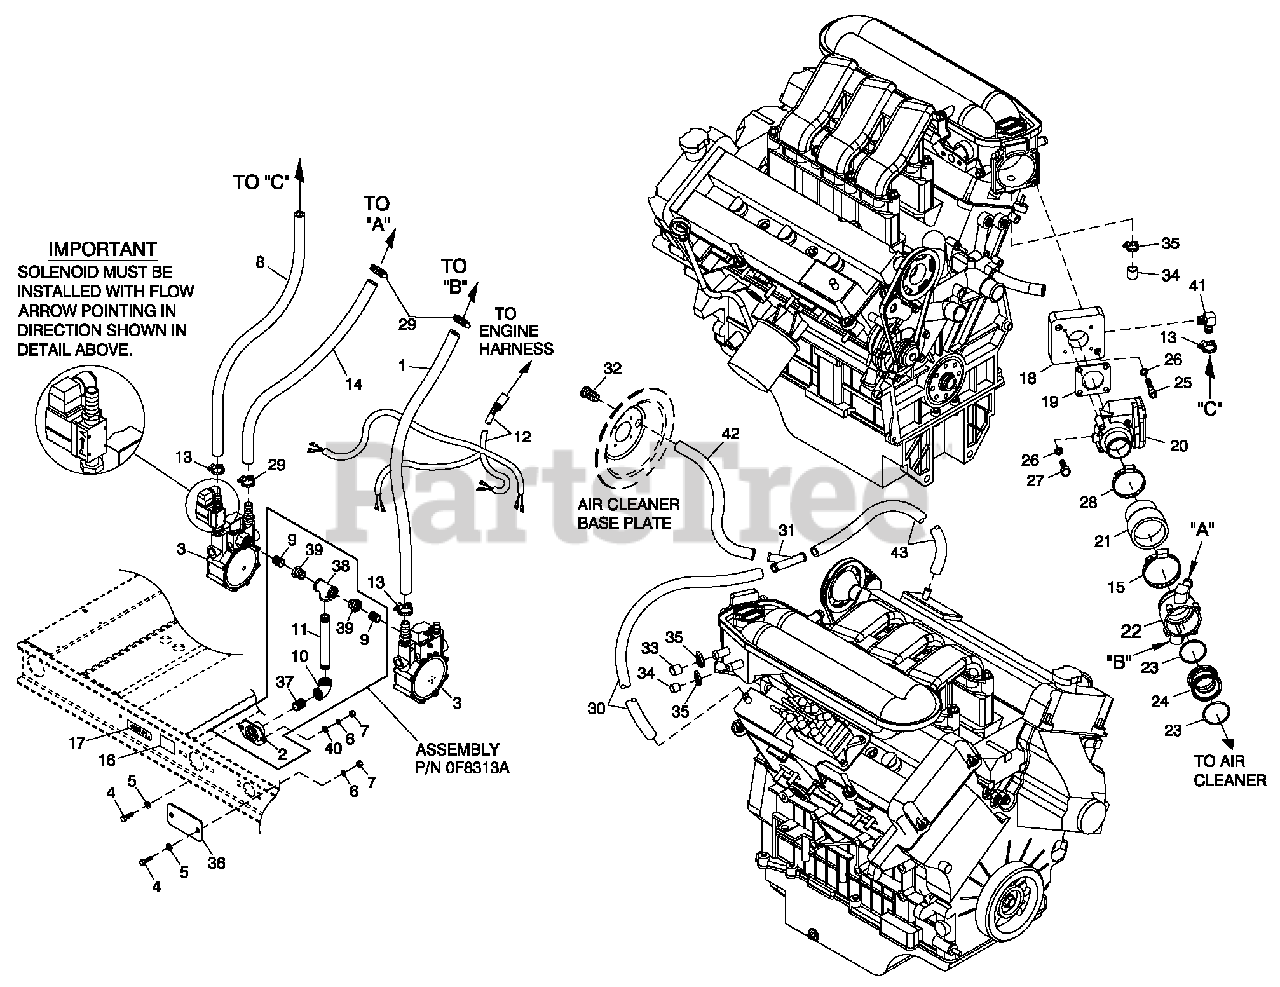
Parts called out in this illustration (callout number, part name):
1	REAR WRAP C4
2	DOOR C4
3	DISCHARGE DUCT LH & RH SIDE C4
4	FRONT CORNERS C4
5	DISCHARGE CENTER DUCT C4
6	ROOF C4ALU M
11	KEY VISE-ACTION LATCH SLOT CIR
12	SCREW THF M6-1 X 16 N WA Z/JS
13	NUT HEX LOCK M6-1.0 SS NY INS
14	RIVET POP .1875 X .450 SS
15	SCREW HWHTF M6-1.0X16
16	NUT H EXM6X1.0G8YEL CHR
17	WASHER SHAKEPROOFINT1/4
18	ASSY WIRE 14AWG 34.8" GRN/YEL
19	INNER DISCHARGE DUCT, C4
20	SCREW HHC M6-1.0X20G8.8
21	SPLITTER C4
22	SPLITTER LOWER C4
23	STRINGER SPLITTER C3
24	SUPPORT SLITTER C4
25	RETAINER INSULATION (820)
26	ASSE MBLY COVER ACCESS
27	WASHER FLAT 1/4- M6ZINC
28	WASHER LOCK M6-1/4
29	NUT HEX 1/4-20 STEEL
30	INSULATION RETAIN MENT HANGER
31	WASHER SELF LOCKING DO ME #4-40
32	INSULATION SPLITTER
33	INSULATION LOWER SPLITTER
34	VISE-ACTION LATCH SLOTTED CIR
35	GASKET EXTRUDED TRI M (374.64" LG)
36	INSULATION DISCHARGE FRONT
37	RETAINER INSULATION (740)
38	RETAINER INSULATION (450)
39	INSULATION DISCHARGE TOP
40	INSULATION ROOFTOP
41	TAB PULL
42	INSULATION LOWER SPLITTER
43	INSULATION DOOR
44	INSULATION REAR WRAP
45	INSULATION CORNER POST
46	INSULATION DISCHARGE SIDE
47	WASHER SELF LOCKING DO ME #8-32
48	STRIP SEALANT 1/8 X 1 (44.52"LG)
